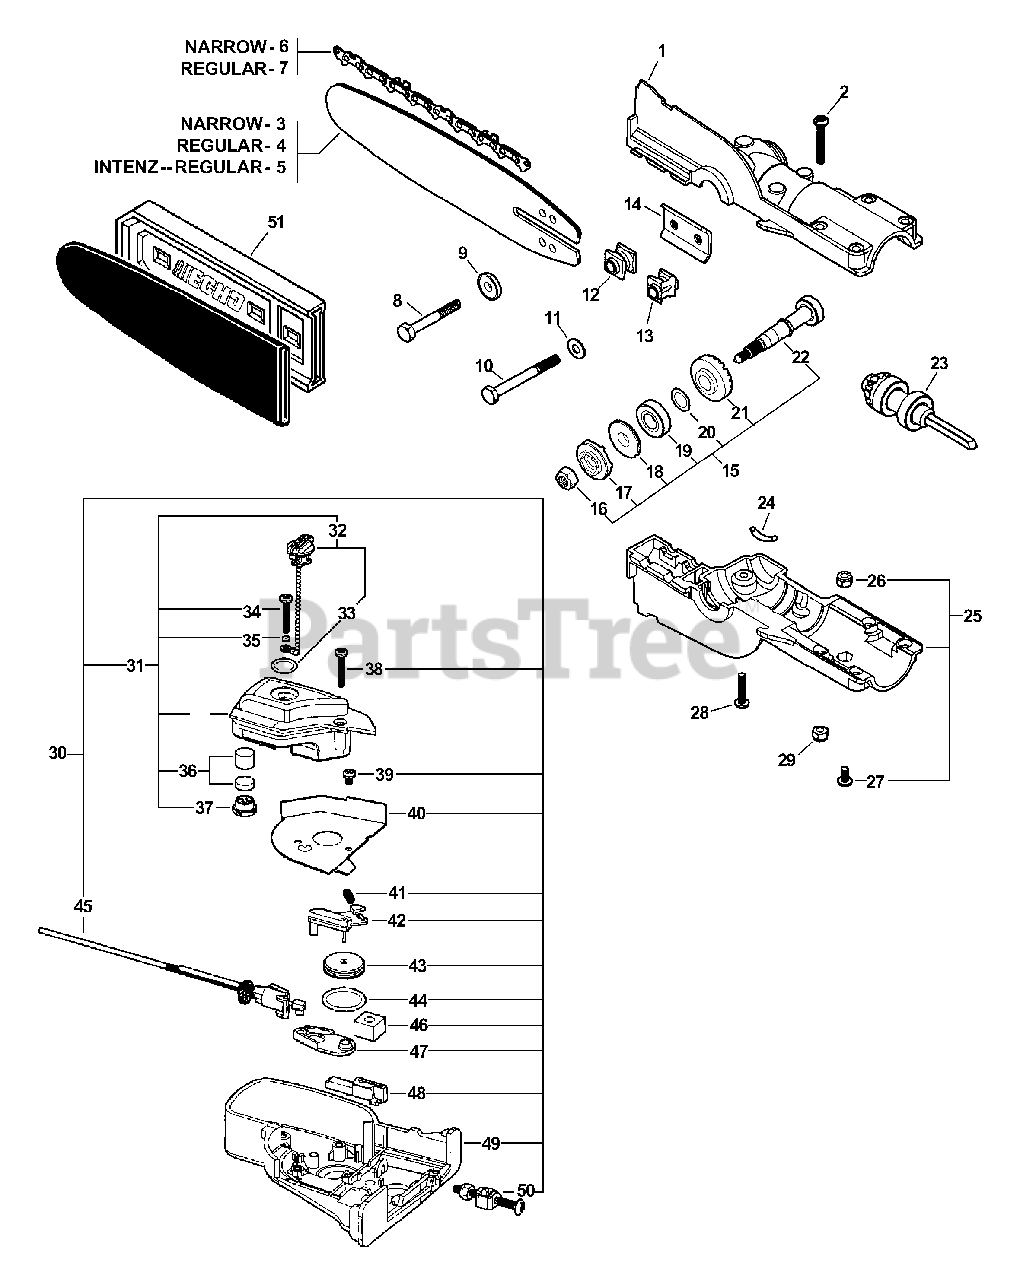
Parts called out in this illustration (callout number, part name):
1	CASE, GEAR - UPPER
2	SCREW - 10-24 X 1-1/4"
3	GUIDE BAR - 12" (30cm)
4	GUIDE BAR - 12" (30cm)
5	GUIDE BAR - 12" (30cm) Intenz
6	SAW CHAIN - 12" (30cm)
7	SAW CHAIN - 12" (30cm)
8	SCREW - 1/4-20 X 1-3/4"
10	BOLT - 1/4-20 X 2-1/4"
12	SPACER
14	BRACKET, GUIDE BAR
15	GEAR SHAFT ASSY
17	SPROCKET, DRIVE
18	SPACER, SPROCKET
19	BEARING, BALL - 6001 DDU
21	GEAR - BEVEL
22	DRIVESHAFT SPROCKET ASSY
23	SHAFT GEAR ASSY
25	CASE, GEAR - LOWER
26	LOCKNUT - 10-24
27	SCREW
28	SCREW - 10-24 X 7/8"
29	LOCKNUT - 10-24
30	AUTO-OILER ASSY
31	OIL TANK ASSY
32	CAP ASSY
36	OIL FILTER ASSY
37	HOUSING, OIL FILTER
42	LINK, OILER IDLER
43	CAM, OIL PUMP
45	AUTO-OILER ASSY
46	SPACER
47	LINK, OILER DRIVE
48	PIPE, OIL OUTLET
49	COVER, OIL PUMP
50	TENSIONER KIT
51	COVER, GUIDE BAR - 12" (30cm)
